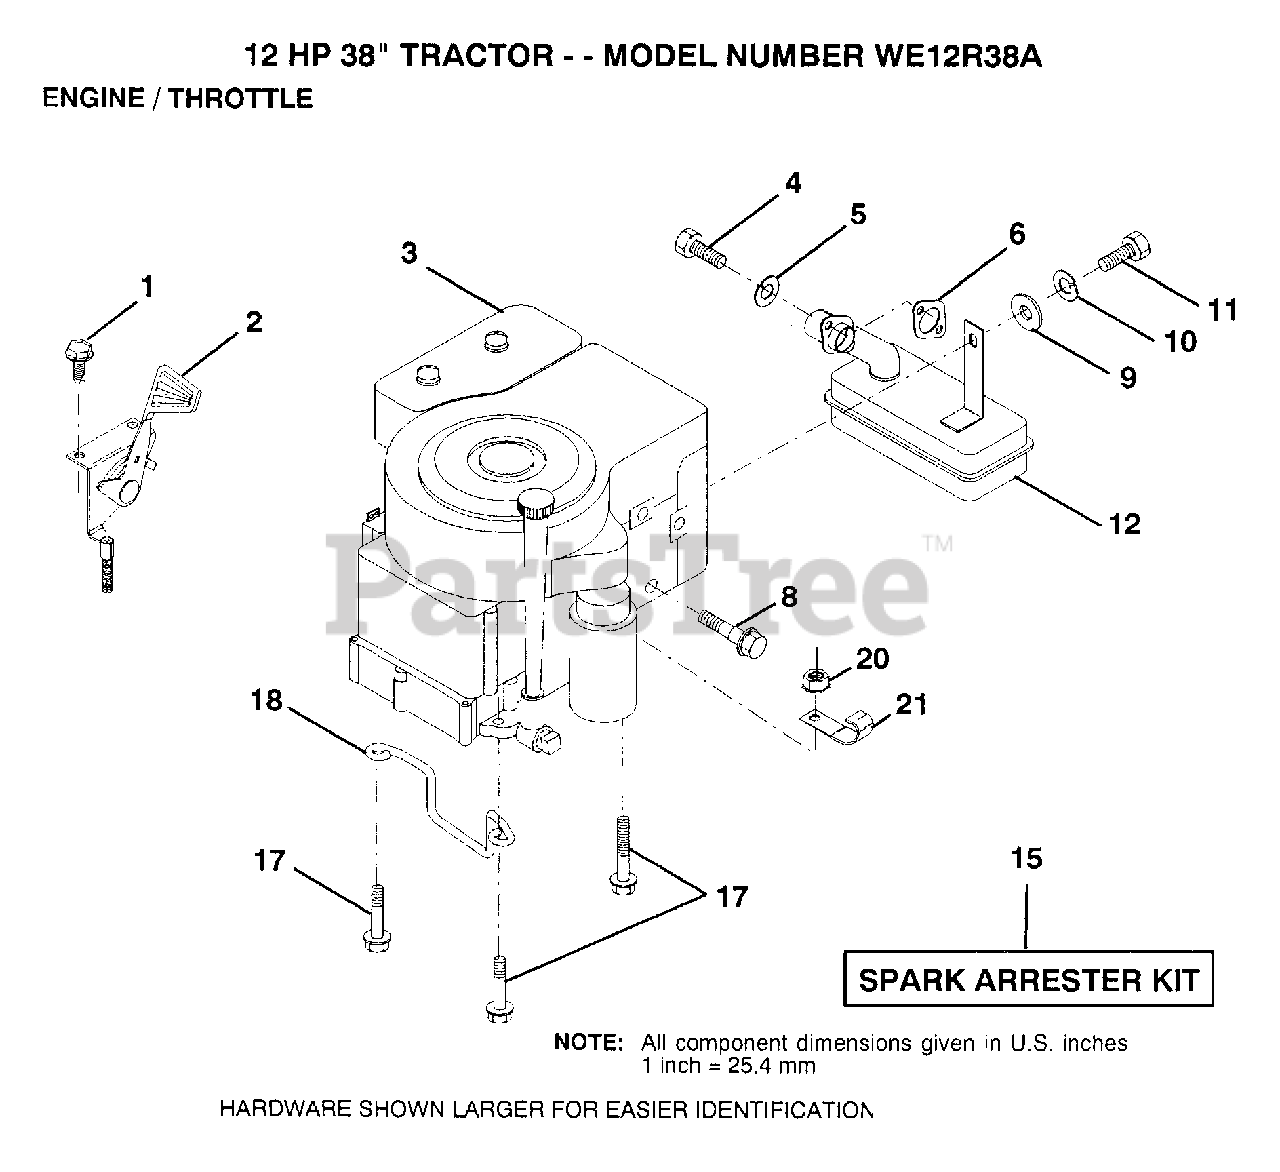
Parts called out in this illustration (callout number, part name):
1	SCREW.1/4-20X1/2
2	THROTTLE CONTROL
4	SCREW
5	LOCKWASHER
8	BOLT T
10	LOCKWASHER
12	MUFFLER
17	SCREW LT
18	"KEEPER,DR BELT GR"
20	NUT
21	CLIP T
